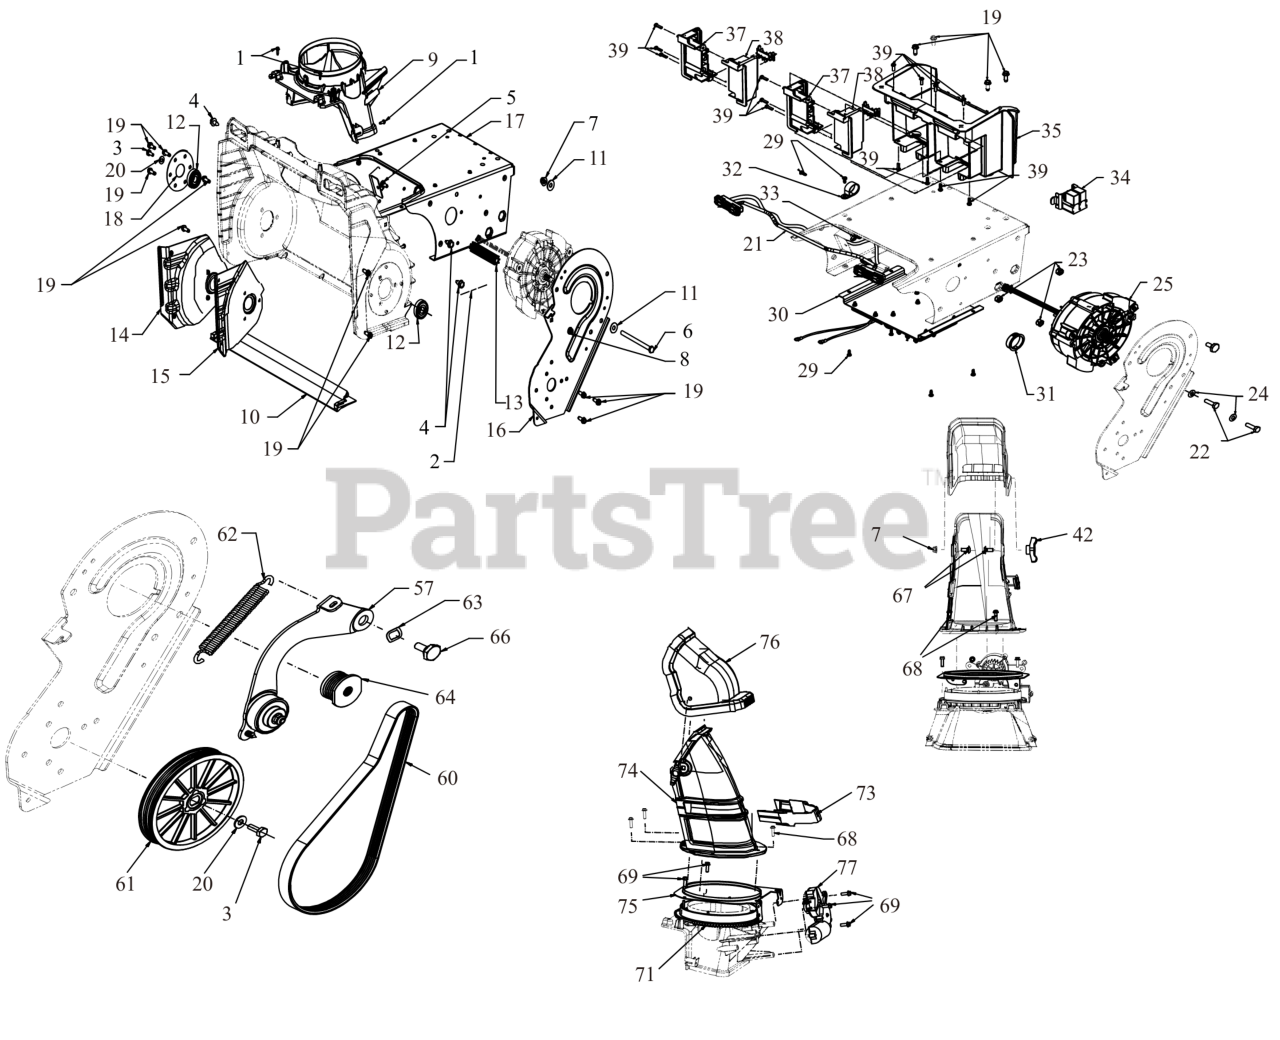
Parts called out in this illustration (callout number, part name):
1	SCREW #8-16 x .50
2	SCREW 8-16X.75
3	BOLT 1/4-28 x .625 GR8
4	SCREW 5/16-18 x .750
5	SCREW 1/4-20 x .75 GR5
6	SCREW 5/16-18 x 4.750 GR5
7	FLANGE LOCK NUT 5/16-18
8	FLANGE LOCK NUT
9	CHUTE ADAPTER
10	SHAVE PLATE 1.019X2.651X20.675
11	FLAT WASHER
12	BALL BEARING
13	SPACER 0.345X0.875X3.895
14	BEARING CUP (RH)
15	BEARING CUP (LH)
16	MOTOR PLATE
17	FRAME
18	BEARING COVER (RH)
19	SCREW-TT-1/4 20X0.75-HXINDWSH
20	FLAT WASHER
21	HEADLIGHT HARNESS (W/LED)
22	HEX HEAD CAP SCREW 5/16-24 x 1.00 GR5
23	HEX NUT
24	FLAT WASHER
25	MOTOR
29	SCREW-TRS-#8-32-0.50-RNDPHI-TYPEF
30	CONTROL
30	CLIP-WIRING-ROSEBUD-ZIPTIE
30	SCREW-TRS-#8-32-0.50-RNDPHI-TYPEF
31	GROMMET 1.31X1.50X0.45
32	DRAIN HOSE CLAMP
33	CLIP-WIRING-ROSEBUD-ZIPTIE
34	BRACKET
34	SCREW-TRS-#8-32-0.50-RNDPHI-TYPEF
35	BATTERY BOX
37	BATTERY RAIL (RH)
38	BATTERY RAIL (LH)
39	SCREW M4.55X16 T20-PLAS THD FRM
42	WING KNOB 5/16-18
57	BRACKET SA
57	FLANGE LOCK NUT
57	SHOULDER SPACER
57	BALL BEARING
57	SOCKET HEAD CAP SCREW 1/4-20-1.25
57	IDLER BRACKET
57	PUSH IN RIVET 0.25X0.63
60	MICRO BELT
61	MICRO PULLEY 5.06
62	EXTENTSION SPRING .625x4.972x.102
63	WAVE WASHER
64	MICRO PULLEY
66	SHOULDER SCREW
67	CARRIAGE BOLT 5/16-18 x .75
68	SCREW M6X22
69	SCREW 1/4-15 x .750
71	BEVEL GEAR 95T
73	CHUTE PLUG
74	LOWER CHUTE 6.5 DIA
75	GEAR BRACKET
76	UPPER CHUTE DEFLECTOR
77	CHUTE ROTATION DRIVE ASSEMBLY
